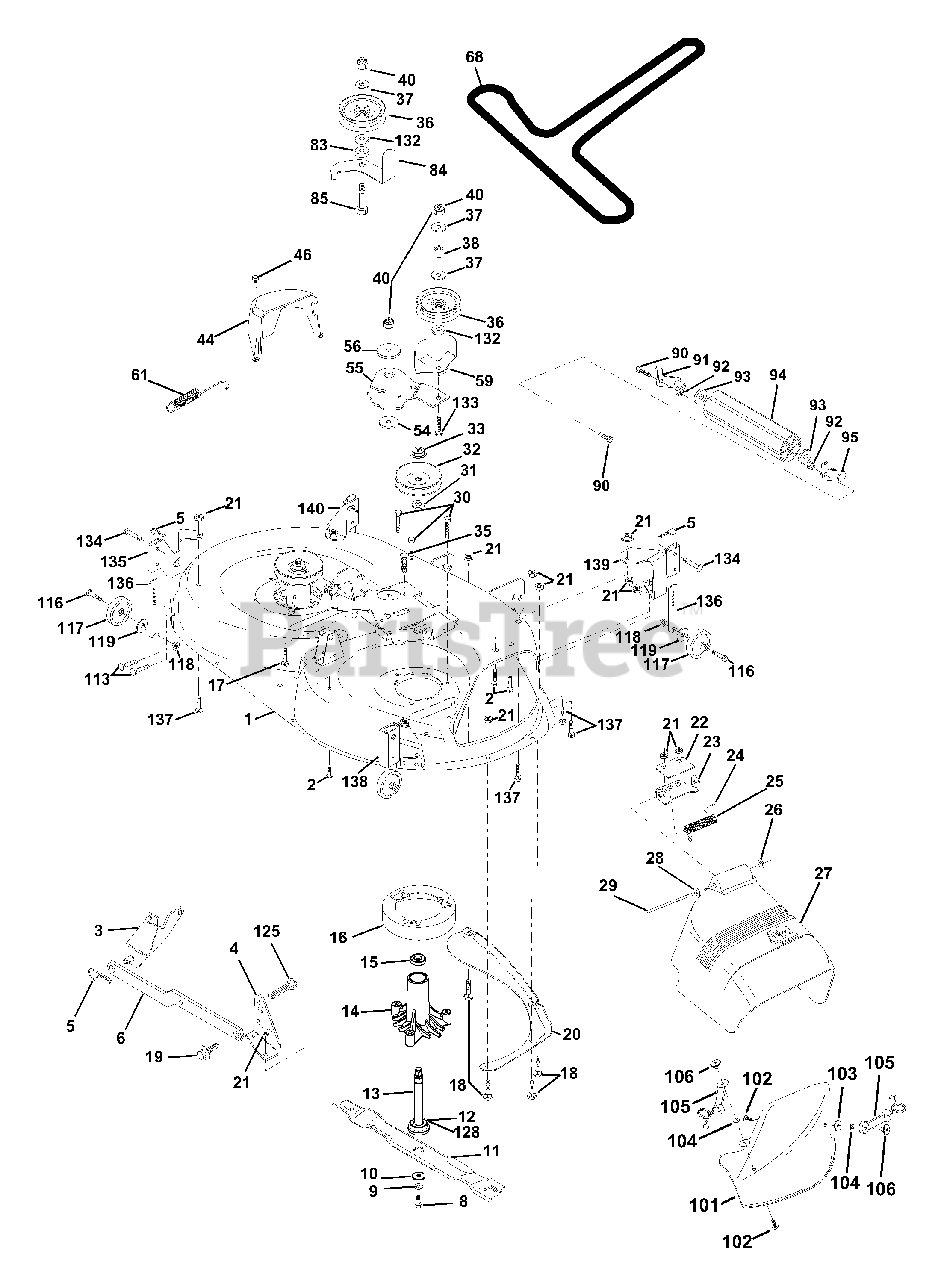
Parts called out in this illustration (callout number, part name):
1	Deck Weldment Mower 42" W/Adj
2	Bolt Rdhd Sqnk 5/16-18unc X3/4
3	Bracket Asm Fr Sway Bar 38/42
4	Bracket Asm Deck 42"sway Bar
5	Retainer Spring
6	Arm Suspension Rear
8	Bolt 3/8-24x1 25 Gr8 Patched
9	Washer Lock Hvy 3/8 Unplated
10	Washer Hard Blade Mower Vented
11	Blade Mower Mulching 42"
12	Bearing Ball #6204 (Mandrel)
13	Shaft Asm W/lower Bearing
14	Housing Mandrel Vented(machd)
15	Bearing Ball Mandrel
16	Stripper Round Mower
17	Bolt Rdhd Sqnk 3/8-16 X 2-1/4
18	Bolt Carr 5/16-18 X 5/8
19	Bolt Shoulder
20	Baffle Vortex 42
21	Nut Crown Lock 5/16-18
22	Stiffener Bracket 42" deck
23	Bracket Deflector Mower 42"
24	Cap Sleeve 80x 112 Blk Mower
25	Spring Torsion Deflector 2 52
26	Nut Push Phos & Oil
27	Shield Deflector Mower 42" Blk
28	Washer 11/32 X 5/8 X 16 Ga
29	Rod Hinge 42"6 75 Wlg
30	Screw Thdrol Washer Head
31	Washer Spacer Mower Vented
32	Pulley Mandrel 42"
33	Nut 9/16top Lock Flng Cntr
35	Fastner Christmas Tree
36	Pulley Idler Flat 3 060
37	Washer 13/32 X 13/16 X 16 Ga
38	Spacer Spring Stop Idler
40	Nut Lock 3/8-16 Unc
44	Guard Mandrel LH Black
46	Screw Thdrol 1/4-20x5/8
54	Washer Hardened
55	Arm Idler 42"mower LT/YT
56	Spacer Retainer Pm Mower
58	Spring Ext Elect CL 38 & 42" Deck
59	Guard, Belt
61	Spring Ext. Elect
68	V-Belt Mower
83	Washer Sintered
84	Keeper 'Belt Idler
85	Bolt Carriage 3/8-16 x 2-1/4 Gr.5
90	Bolt Fin Hex 3/8-16unc X 1
91	Bracket Asm Noseroller LH
92	Nut Lock Hex w/ins. 3/8-16 UNC
93	Washer 17/32 X 7/8 X 16 Ga
94	Roller Nose 38 & 42
95	Bracket Asm Noseroller RH
101	Cover Mulching 42" Blk
102	Screw
103	Washer #10
104	Washer Lock #10
105	Latch Asm Bagger
106	Nut Weld .327/.304 #10-24
116	Bolt Shld
117	Wheel Gauge blk.
118	Nut Centerlock 3/8 - 16 UNC
119	Washer 3/8 x 7/8 x 14 Ga.
125	Cotter Pin
128	Washer Felt
130	Bolt Fin Hex 3/8-16 UNC x 1 Gr. 5
132	Washer 13/32 x 1-3/8 x 3 Ga
133	Bolt Rdhd 3/8-16 UNC x 2-3/4 Gr.5
134	Pin Head Rivet
135	Bracket Asm Whl Ga Rear LH 42"
136	Bar Pnt Adjusting Wheel Gauge
137	Bolt Carr 5/16-18 x 5/8 Short
138	Bracket Asm Whl Ga. Rear RH 42"
139	Bracket Asm Whl Ga. Front RH 42"
140	Bracket Asm Whl Ga. Front RH 42"
